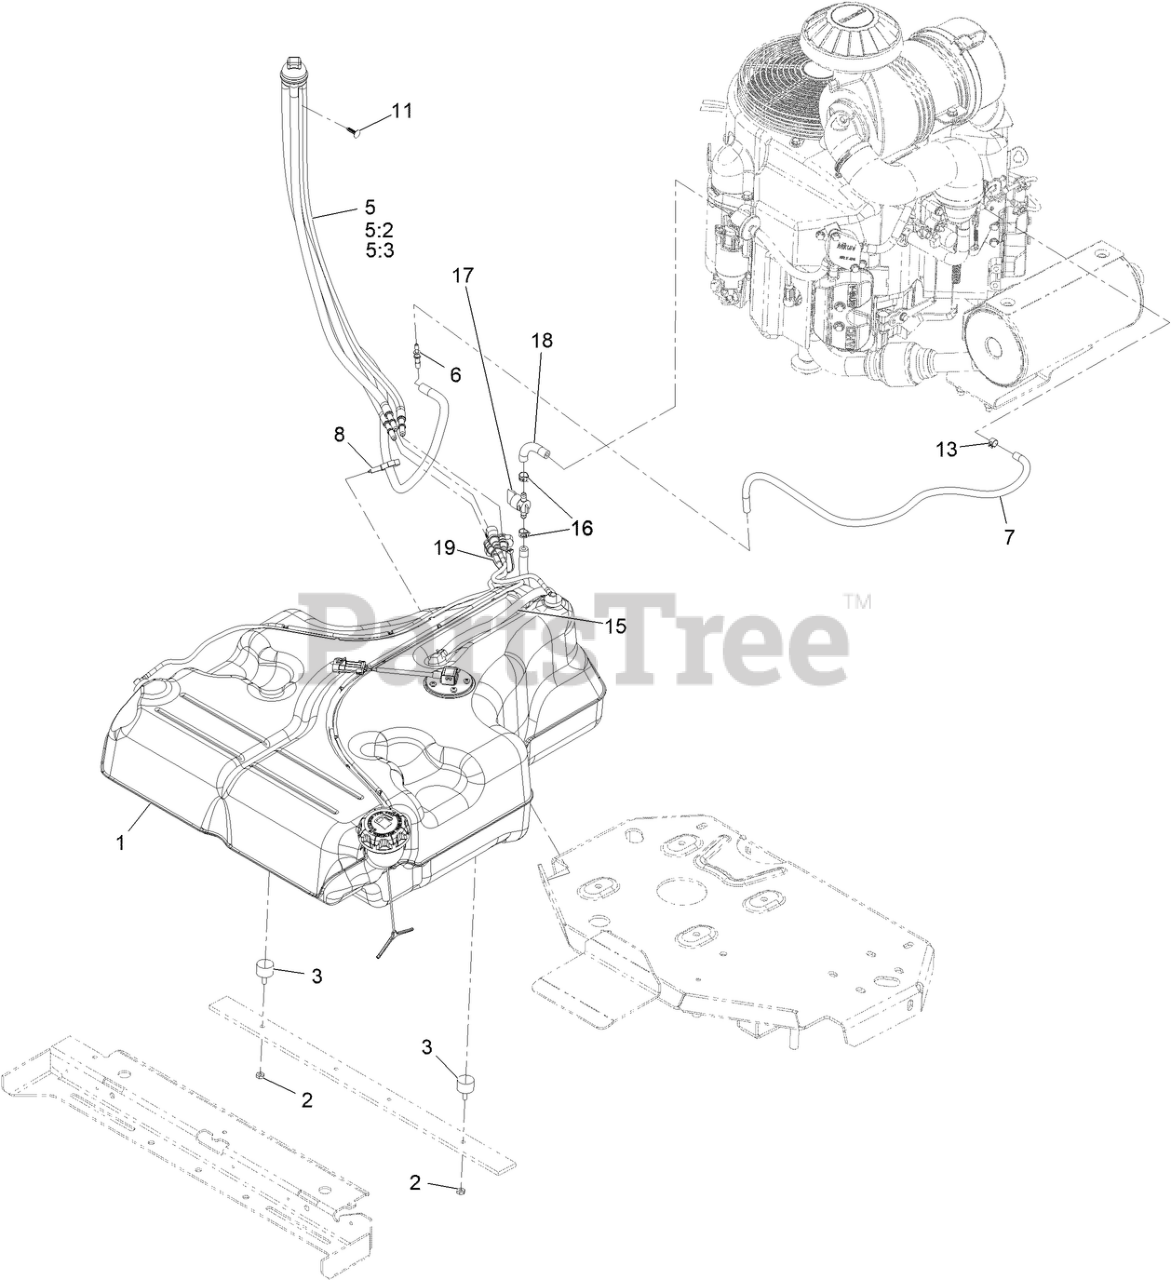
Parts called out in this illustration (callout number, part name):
1	FUEL TANK ASM
2	NUT-JAM
5	FUEL MANIFOLD VENT ASM
5:2	HOSE-FUEL
5:3	HOSE-FUEL
6	BARB-FUEL
7	Hose-Fuel
8	CLAMP-HOSE
11	PLUG-PLASTIC
13	CLAMP-HOSE
15	HOSE-FUEL
16	CLAMP-HOSE
17	VALVE-FUEL
18	HOSE-FUEL
19	TIE-CABLE
